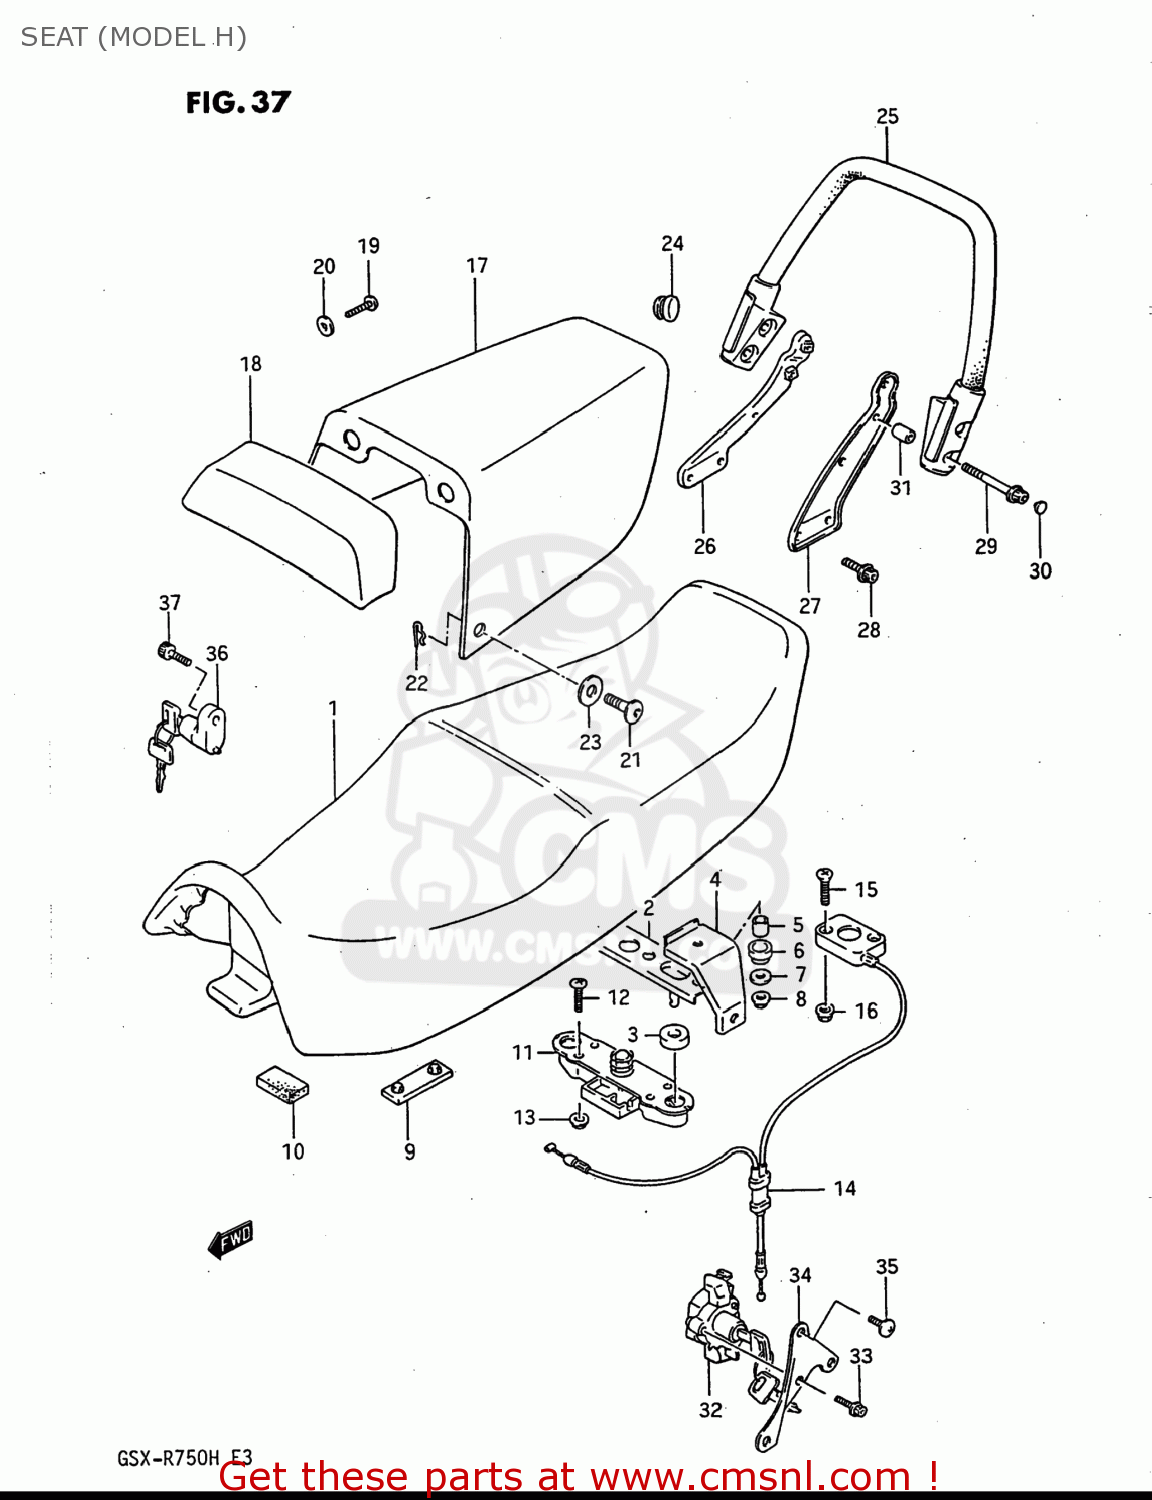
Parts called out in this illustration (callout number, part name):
1	SEAT ASSEMBLY
2	STRIKER,SEAT LOCK
3	CUSHION
4	PLATE,SEAT GRIP BAND
5	SPACER
6	CUSHION
7	WASHER
8	NUT
9	CUSHION
10	CUSHION
11	LOCK ASSY,SEAT STRIKER
12	SCREW
13	NUT
14	BRACKET,SEAT SUPPORT RR
15	SCREW
16	NUT
17	BOX SET,SEAT TAIL
18	BACKREST,SEAT
19	SCREW, CENTER
20	WASHER (6.5X18X1.6)
21	BOLT
22	CLIP
23	WASHER(10X25X3.2)
24	CAP,SEAT TAIL COVER
25	HANDLE,PILLION RIDER
26	PLATE,PILLION HANDLE,R
27	PLATE COMP,PILLION HANDLE
28	BOLT
29	BOLT
30	CAP(OD:10)
31	SPACER (8.6X13.8X21.5)
32	LOCK SET
33	PLUG ,6X20
34	BRACKET,SEAT LOCK
35	SCREW 6X12
36	LOCK SET
37	BOLT
